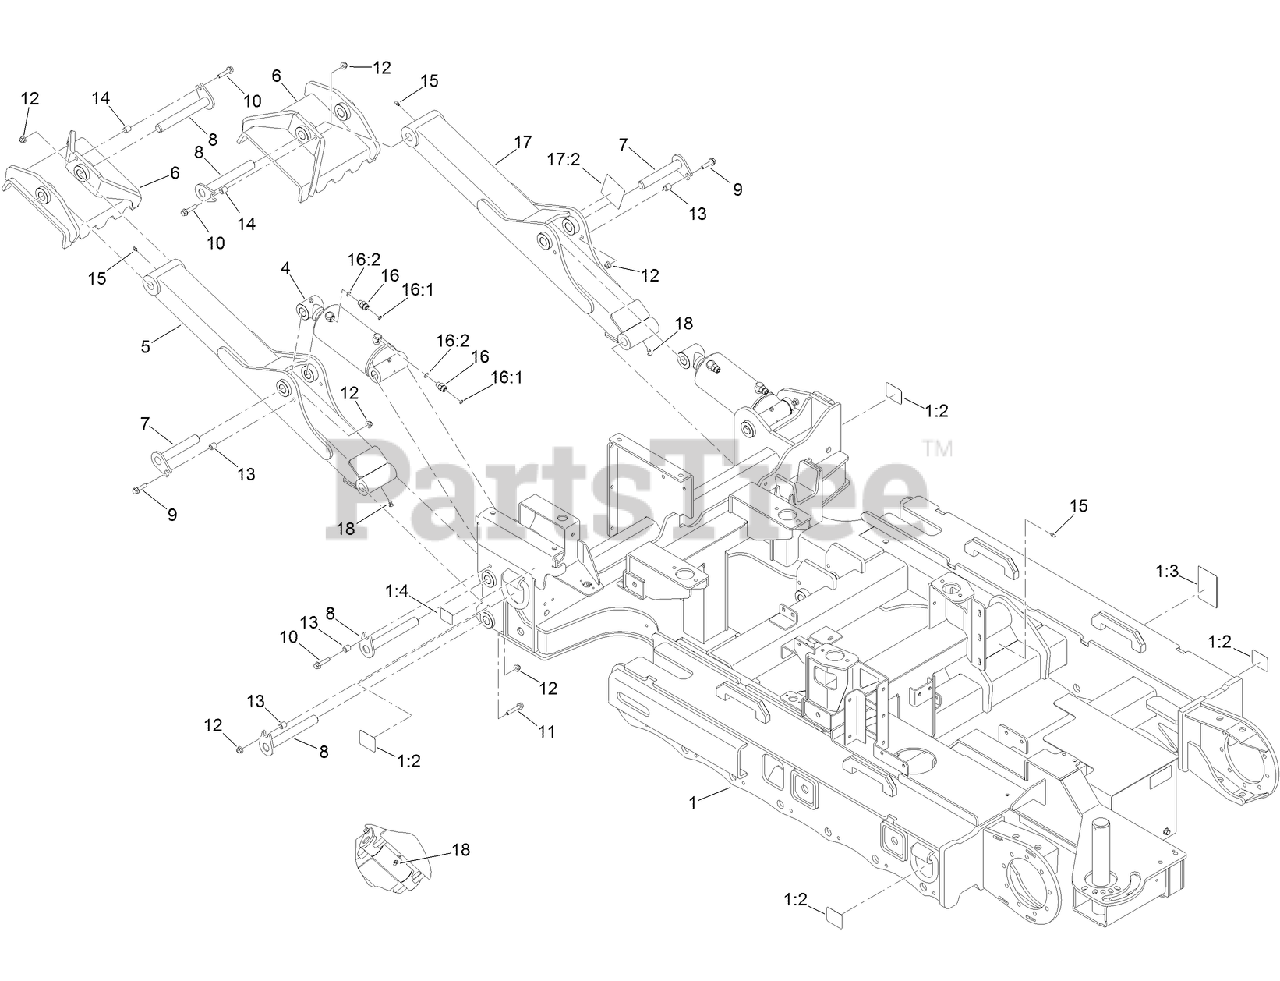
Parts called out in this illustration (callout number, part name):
1	MAIN FRAME ASM
1:2	DECAL-TIE DOWN
1:3	DECAL-WARNING, THROWN OBJECTS
1:4	DECAL-DRAIN, OIL
4	HYDRAULIC CYLINDER ASM
5	LEG-STABILIZER
6	FOOT-STABILZER, LH
7	PIN-PIVOT
8	PIN-FLAG
9	SCREW-HHF
10	SCREW-HHF
11	SCREW-HHF
12	NUT-HF, NI
13	SPACER
14	SPACER
15	FITTING-GREASE
16	FITTING-STRAIGHT
16:1	O-RING
16:2	O-RING
17	LH STABILIZER LEG ASM
17:2	DECAL-WARNING
18	FITTING-GREASE
